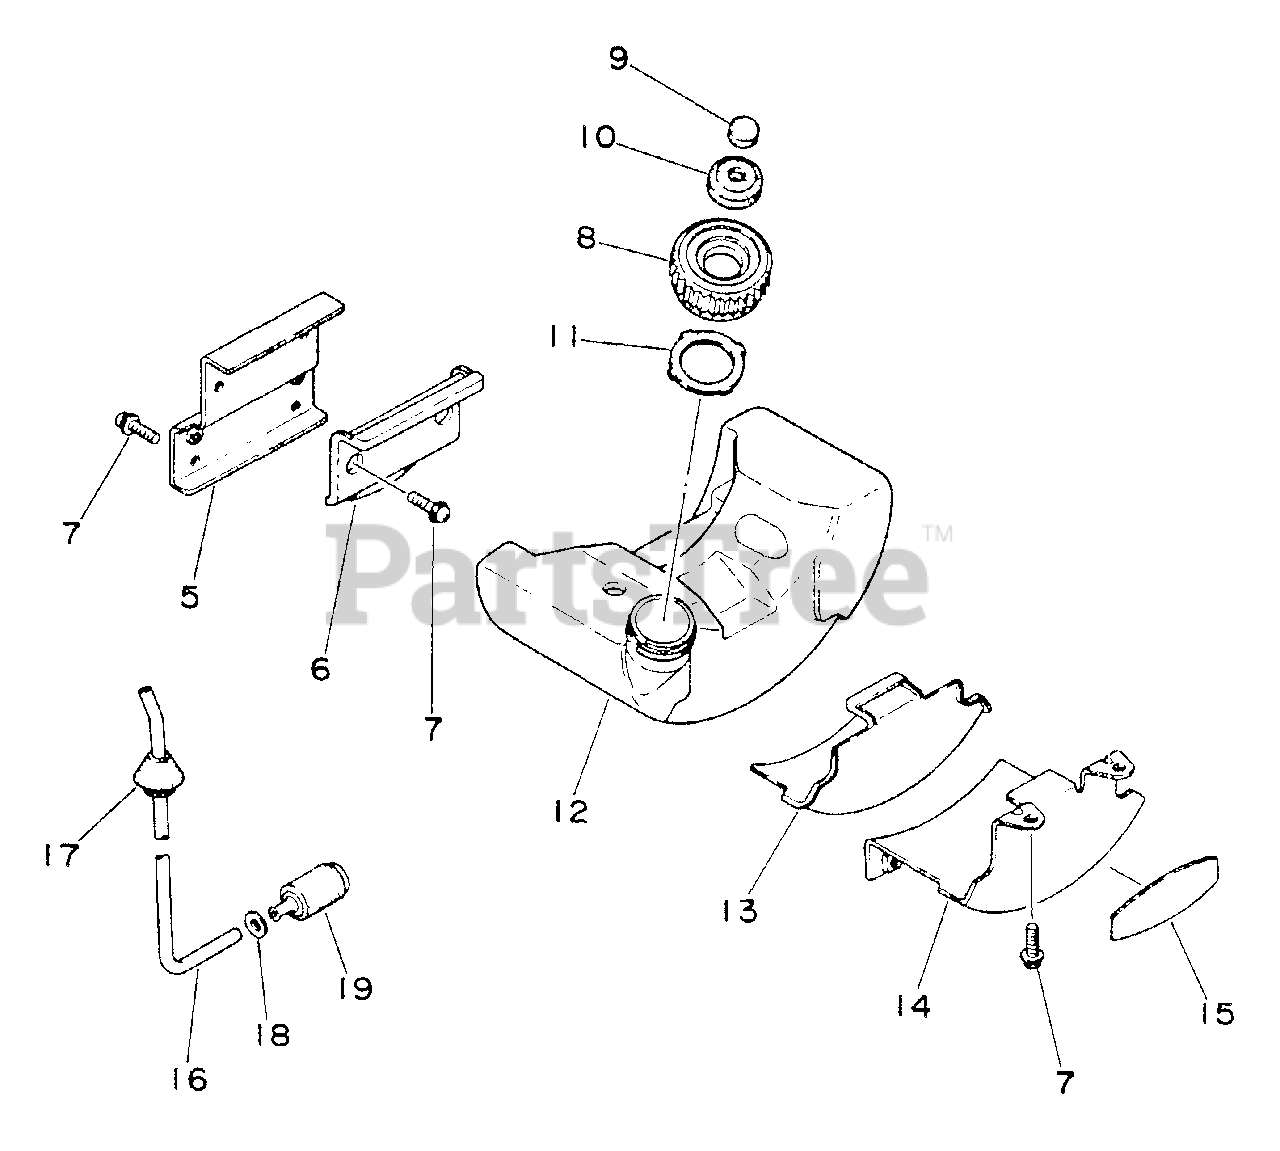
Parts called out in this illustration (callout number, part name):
5	BRACKET, FUEL TANK
6	CUSHION, FUEL TANK
7	SCREW - 4X14
8	CAP ASSY
11	GASKET, CAP
12	TANK, FUEL
14	BRACKET, FUEL TANK
15	LABEL - ECHO
16	PIPE - 3X6X135 -- BLACK
18	WASHER - 5
19	FILTER, FUEL
